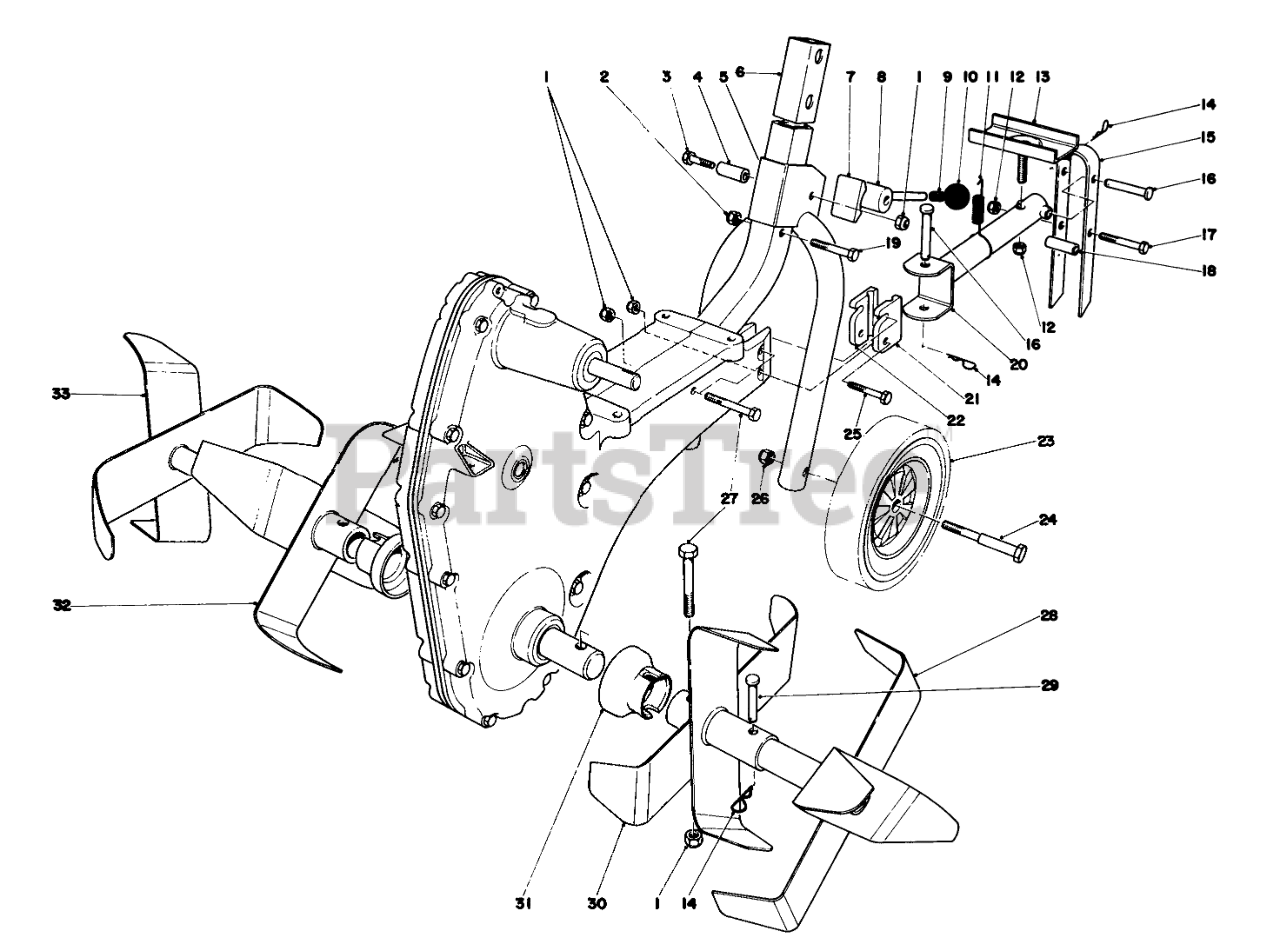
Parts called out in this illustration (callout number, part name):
1	NUT-HEX, SIDE DEFORM
2	NUT-HEX, SIDE DEFORM
3	SCREW-HH
4	CAM SPACER
5	Wheel Support
6	Lower Handle
7	Cam Shoe
8	Cam Lever
9	Tolerance Ring
11	Spring
12	NUT-LOCK, SIDE
13	Drawbar Stop
14	PIN-COTTER
15	Dragbar
16	PIN-CLEVIS
17	SCREW-HH
18	Spacer
19	SCREW-HH
20	Drawbar
21	LH PIVOT BLOCK
22	Pivot Block R.H.
23	WHEEL TIRE ASM 8 IN
24	Wheel Bolt
25	SCREW-HH
26	NUT-LOCK, CONE
27	SCREW-HH
28	Outboard Tine L.H.
29	CLEVIS
30	Inboard Tine L.H.
31	Dust Cover
32	Inboard Tine R.H.
33	Outboard Tine R.H.
